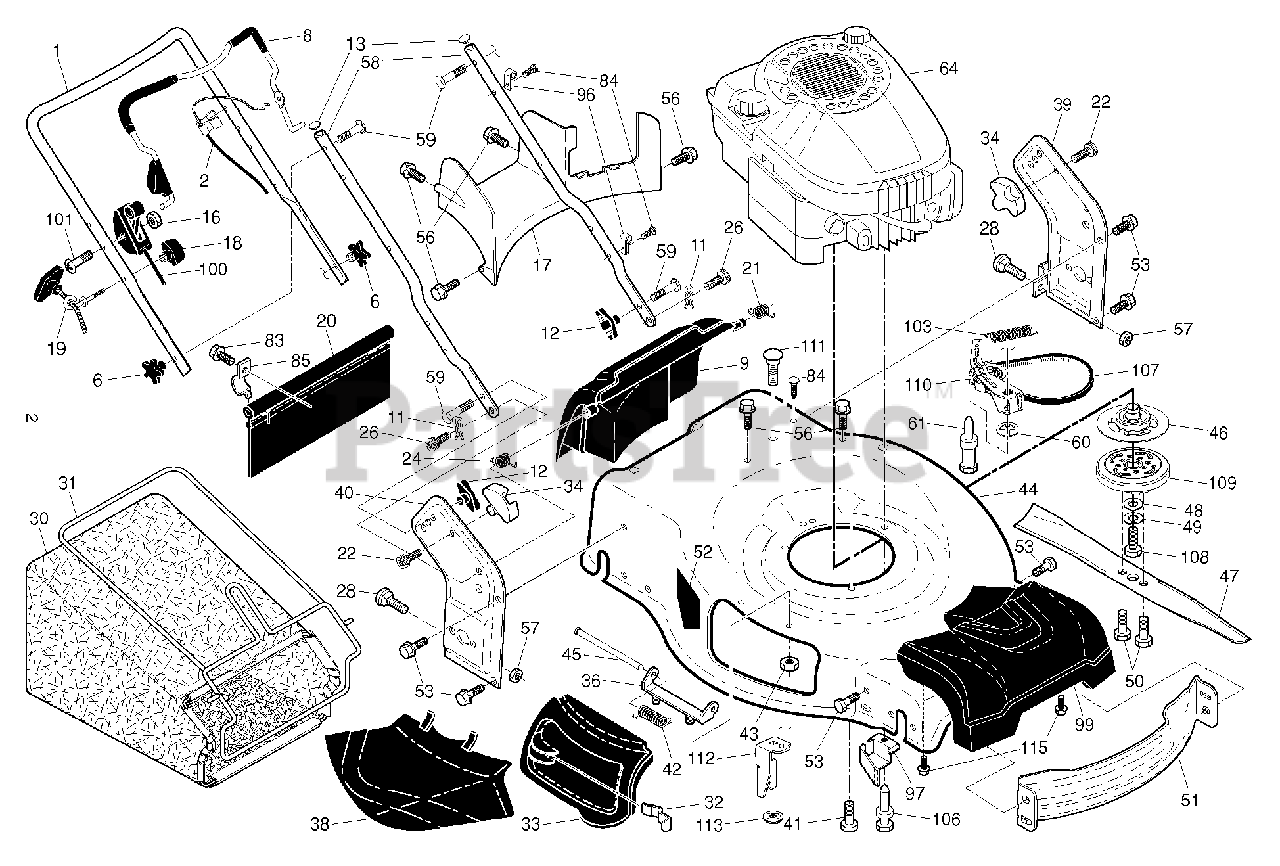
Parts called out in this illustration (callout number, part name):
1	HANDLE.UPPER.3.POS.BS.AW2.GREY
2	CABLE.BBC.22+.AW2.BS.ERGO.WALK
6	KNOB.HANDLE.PLASTIC.STAR.BLACK
8	RP.LVR ASMBBC.EN.ERGO.OM.OR/OR
9	DOOR.REAR.ASM.22+.HUSQ.FG/RGD
11	COTTER.HAIRPIN.DOOR/HANDLE.PIV
12	KNOB, DEFLECTOR
13	PLUG.PLASTIC.7/8".14-20.GAUGE
16	NUT
17	BAFFLE.REAR.22+RGD.AWD.PLASTIC
18	T-KNOB.NEW ROPE GUIDE
19	GUIDE.ROPE.BLK.ZINC.CHROM
20	SKIRT.REAR.22PLUS.RGD.LW(2 2MC
21	SPRING.LH.BLACK
22	SCREW.PAN.HEAD.#10
24	SPRING.RH.GRAY
26	SCREW,DOOR/HANDLE.PIVOT
28	BOLT.CARRIAGE.LN.5/16-18X.5/8
30	GBAG.BA85028ER.GRY/ORG
31	FRAME.GBAG.22+.BLK
32	LATCH.DOOR.ZINC
33	DOOR.MULCH.22 PLUS.HUSQ.GREY
34	BRACKET.GRASSBAG.ATTACHING.BLK
36	BRACKET.ASM.HINGE.21.FWGD.
38	DEFLECTOR.CLIPPING.22.BLACK
39	BRACKET.ASM.HANDLE.LT.22+.GREY
40	BRACKET.ASM.HANDLE.RT.22+.GREY
41	BOLT 3/8-16X1-1/8
42	SPRING.TORSION
43	NUT.HEX.FLANGE.1/4
44	HOUSING.22+RG.MC.WO.BBC.668.TR
45	ROD.HINGE.21
46	PULLEY.BBC.DRIVING
47	BLADE.22.4-N-1.BBC.
48	WASHER.CRANK.BOLT
49	LOCKWASHER
50	BOLT.BLADE
51	BAFFLE.FRONT.22.PLUS
52	DANGER DECAL
53	BOLT.5/16HEX.WHS.HD
56	SCREW.HX.13X.750
57	NUT.FLANGE.5/16
58	HANDLE.LOWER.22+BT.2PC.GRY
59	BOLT, HANDLE 5/16-18X1.75
60	E-RING.12MM.SHAFT
61	BOLT.BBC.TENSION.PIVOT
83	TAPPING SCREW
84	FASTENER.PUSH.O.250X0.783
85	BRACKET.SKIRT.22+.BZP
96	CLIP.CABLE.BLK
97	BRACKET.BELT.GUIDE.22+.BZP
99	COVER.ASM.FRONT.HUSQ.22+RGD
100	CONTROL.THROTTLE.BBC
103	SPRING.BRAKE.RESET
106	BOLT.BRAKE.RESET.SPRING
107	BELT.COG.BBC
108	SCREW, HEX HD 3/8-24 X 1-3/8
109	HUB.FREE.BBC.ASSEMBLY(2 2MC)
110	ARM.BBC.TNSION.ARM.PULL(2 2MC)
112	BRACKET.CABLE MOUNTING.22+
113	NUT.FLANGE.1-4-20-SERR
115	SCREW.HI-LO. 5/16 X 1.00
